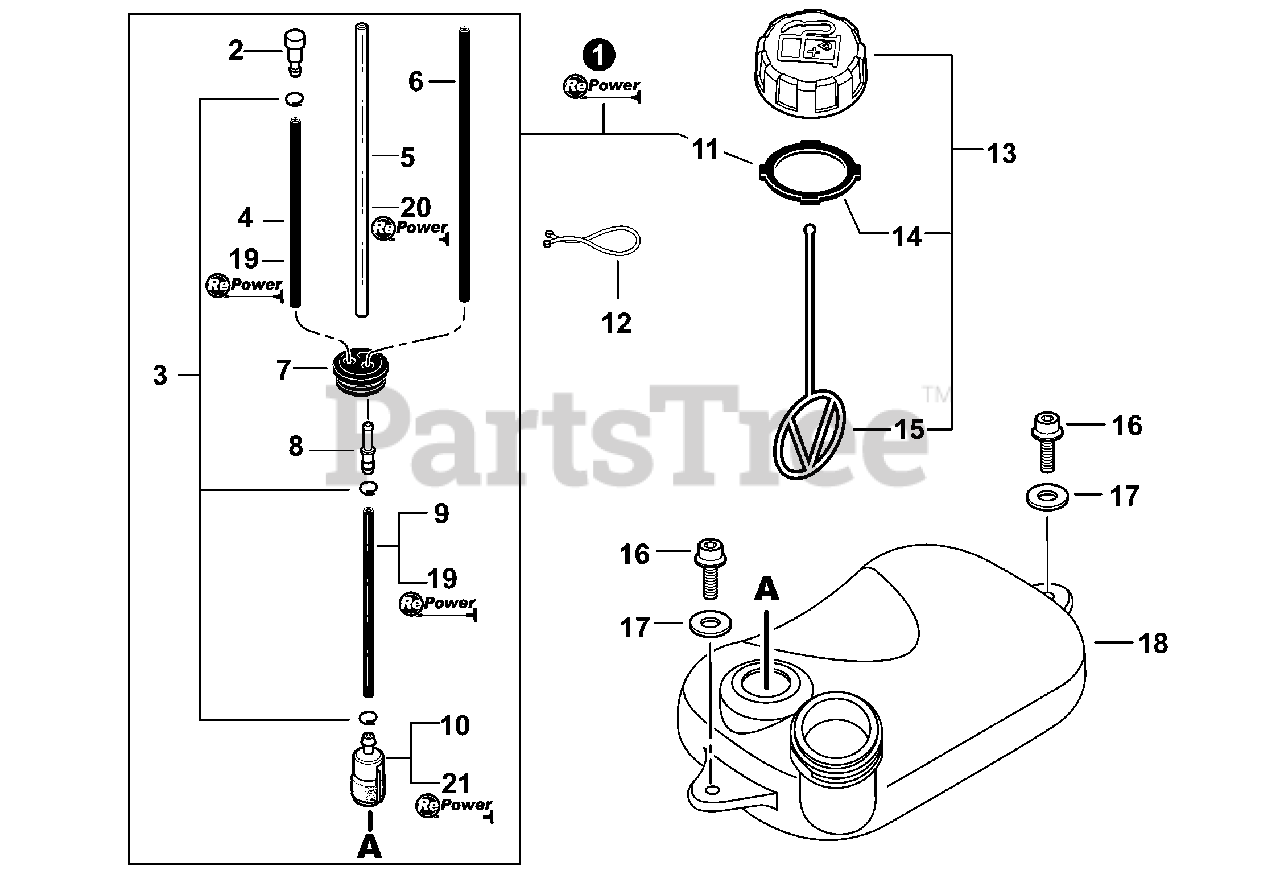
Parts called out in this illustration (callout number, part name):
1	FUEL SYSTEM KIT
2	VENT ASSY
3	CLIP Ø6
4	PIPE, FUEL 3x-5x-70 BLACK
5	PIPE, FUEL 3×6×125
6	PIPE, FUEL - 3×5×120 - BLACK
7	GROMMET, FUEL
8	CONNECTOR, PIPE Ø5ר3.5
9	PIPE, FUEL 3×5×90 BLACK
10	FILTER, FUEL
11	GASKET, FUEL CAP
12	CLIP, TUBE
13	CAP ASSY, FUEL
14	GASKET, FUEL CAP
15	CONNECTOR, CAP L= 100 MM
16	BOLT 5×20
17	WASHER 5.5×16×2T
18	TANK, FUEL
19	BULK PIPE - 3×5 MM BLACK (4 PIECES×2 M)
20	BULK PIPE - 3×6 MM CLEAR (4 PIECES×2 M)
21	TUNE-UP KIT - REPOWER
